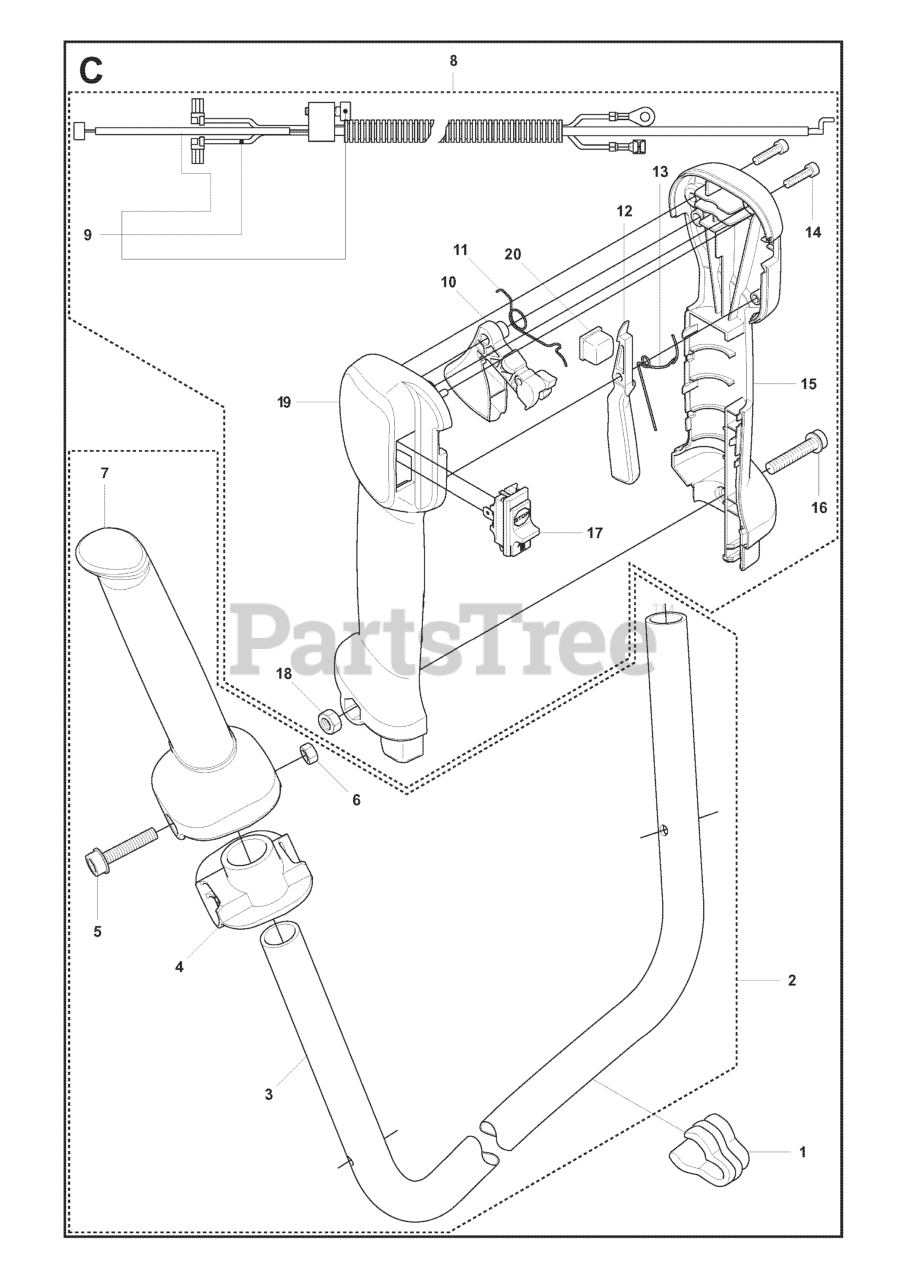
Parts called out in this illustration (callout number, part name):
8	HANDLE SYSTEM ASSY OPS, SOFT
9	WIRING ASSY ICE AUGER
10	THROTTLE TRIGGER
12	THROTTLE LOCK
16	SCREW
17	STOP BUTTON
19	HANDLE HALF LEFT
